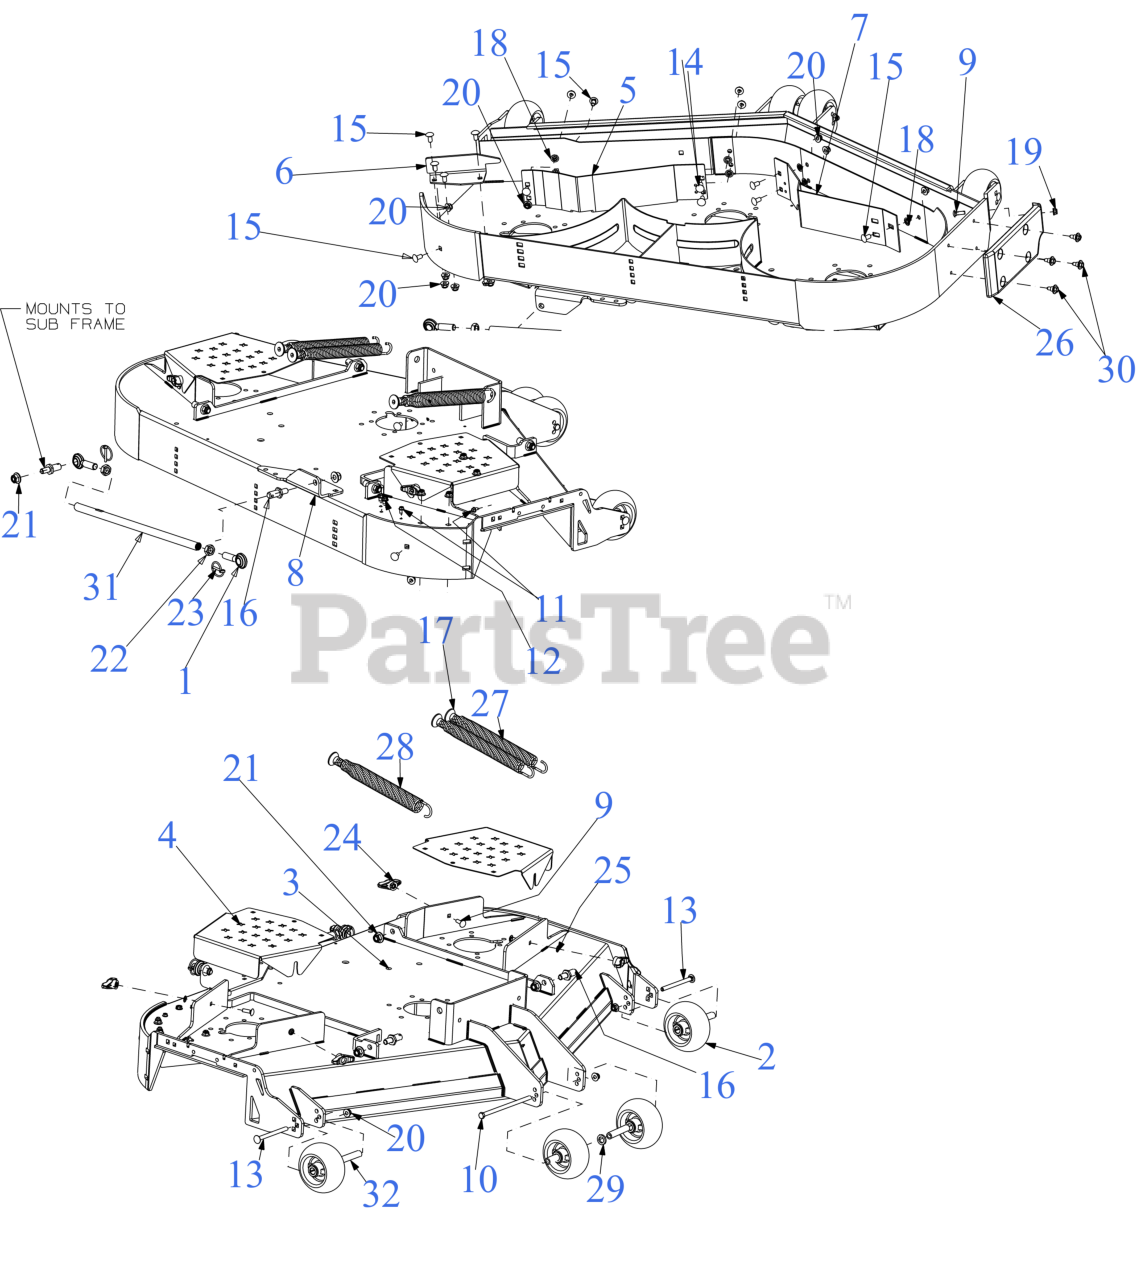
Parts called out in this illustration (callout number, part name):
1	MALE ROD END
2	5" DIA DECK WHEEL COMPLETE
3	54" FAB DECK SHELL
4	DECK BELT COVER
5	DECK BAFFLE
6	DECK CHUTE BAFFLE
7	BAFFLE
8	DECK BELT GUIDE BRACKET
9	CARRIAGE BOLT 5/16-18 x 1.00
10	SCREW 3/8-16 x 7.25 GR5
11	SCREW 1/4-20 X.500
12	SCREW 5/16-18 x .500
13	CARRIAGE BOLT 3/8-16 x 4.25 GR5
14	CARRIAGE BOLT 3/8-16 x 1.00 GR5
15	CARRIAGE BOLT 3/8-16 x .75
17	SPRING INSERT SCREW
19	FLANGE LOCK NUT 5/16-18
22	HEX JAM NUT 5/8-18
23	LYNCH PIN .1875
24	WING KNOB 5/16-18
26	DECK SKID PLATE (LH)
27	EXTENTION SPRING 1.20 x 11.35
28	EXTENSION SPRING 1.44 OD x 11.36
29	FLAT WASHER .632X1.00X.16
30	SHOULDER SCREW .43X.29X5/16-18 TT
31	TUBE .565 X .750 X 18.75"LG
32	WHEEL SPACER .38ID x 3.04LG
